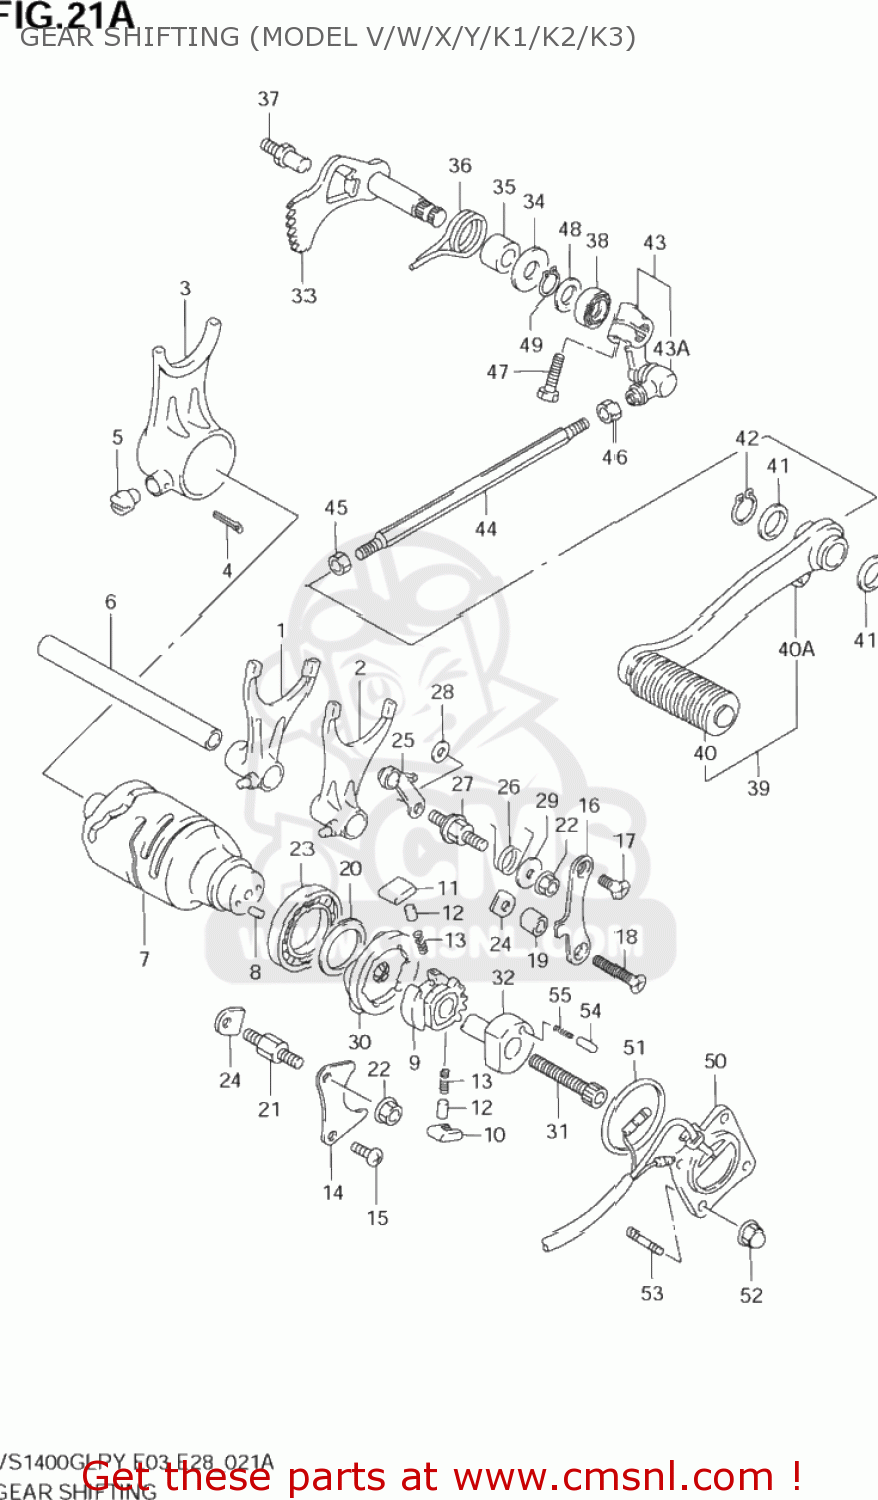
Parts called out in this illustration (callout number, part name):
1	FORK,GEAR SHIFT NO.1
2	FORK,GEAR SHIFT NO.2
3	FORK,GEAR SHIFT NO.3
4	PIN, COTTER
5	PIN
6	SHAFT,GEAR SHIFT FORK(L:152)
7	CAM,GEAR SHIFT
8	PIN
9	GEAR,GEARSHIFT CAM DRIVE
10	PAWL,GEAR SHIFT NO.1
11	PAWL,GEAR SHIFT NO.2
12	PIN(5X8)
13	SPRING
14	LIFTER,GEAR SHIFT POLE
15	SCREW
16	GUIDE,GEAR SHIFT CAM
17	SCREW
18	SCREW
19	SPACER(6.5X10X14)
20	WASHER(25X32X3)
21	BOSS,SHIFT PAWL LIFTER
22	NUT
23	BEARING(25X47X8)
24	RETAINER
25	STOPPER,GEAR SHIFT CAM
26	SPRING
27	SUPPORT,CAM STOPPER ARM
28	WASHER
29	WASHER (6.5X18X2)
30	PLATE,GEAR SHIFT CAM
31	BOLT
32	HOLDER,NEUTRAL SWITCH
33	SHAFT,GEAR SHIFT
34	WASHER(12.5X28X1.2)
35	SPACER(12X20X15.3)
36	SPRING
37	STOPPER,SHIFT ARM
38	OIL SEAL
39	LEVER ASSY,GEAR SHIFT
40	RUBBER,GEAR SHIFT PEDAL
40A	COVER,DUST
41	WASHER(14.5X22X1)
42	CIRCLIP
43	ARM,GEAR SHIFT LINK
43A	COVER,DUST
44	ROD,GEAR SHIFT LINK
45	NUT
46	NUT
47	BOLT
48	SHIM(12X20X1)
49	CIRCLIP,12 MM
50	BASE ASSY,NEUTRAL SW TERMINAL
51	O RING(D:2.4,ID:35.5)
52	NUT
53	BOLT,STUD
54	PIN
55	SPRING
